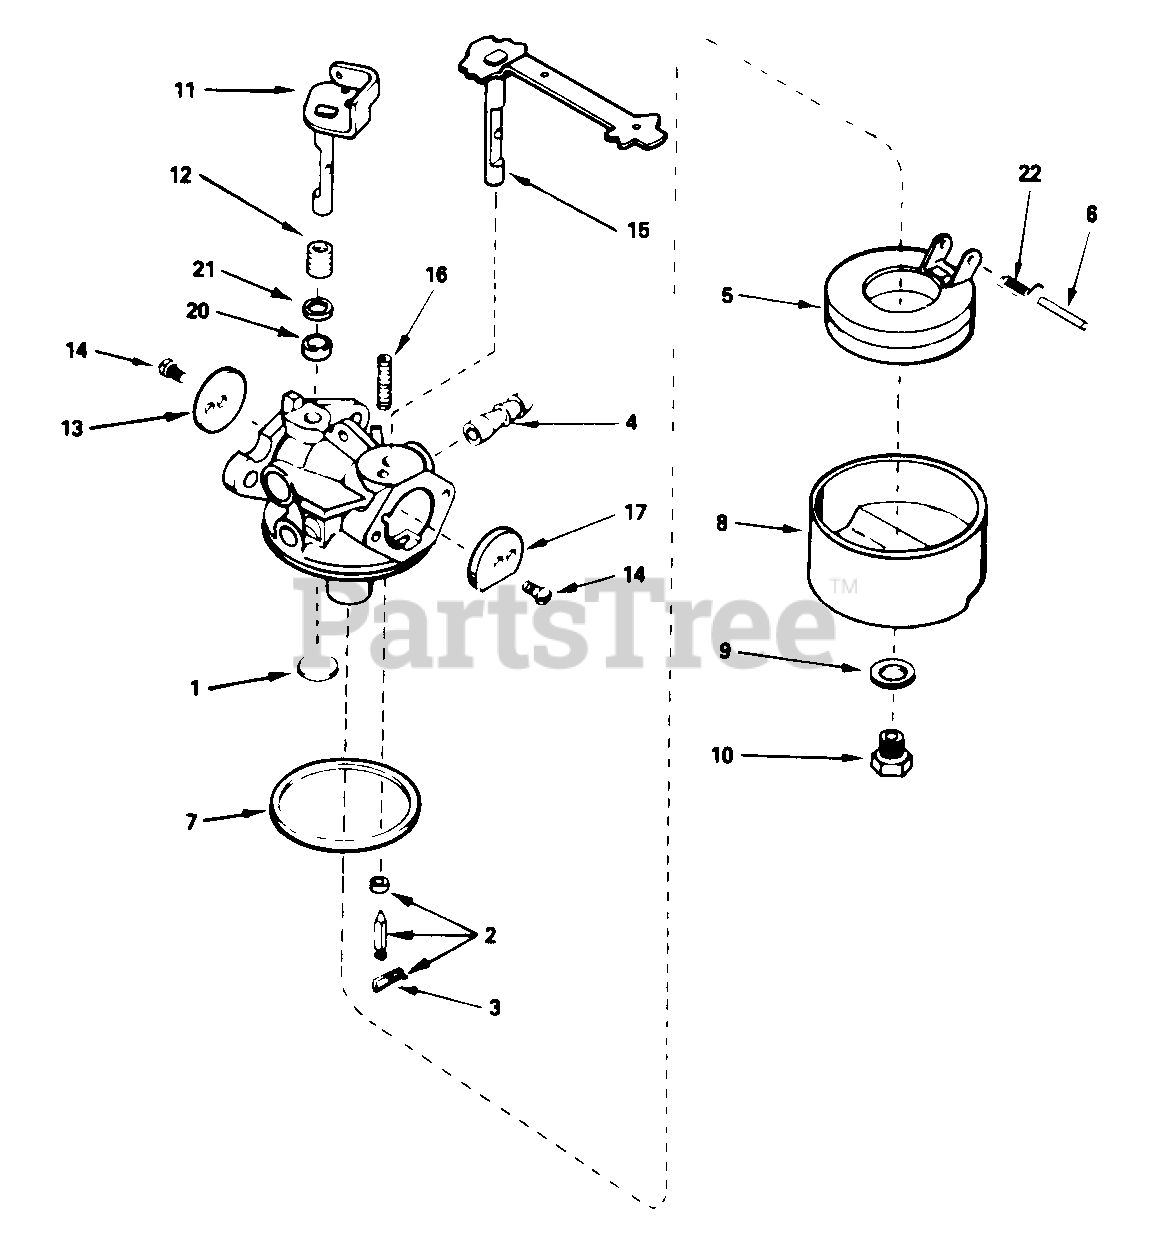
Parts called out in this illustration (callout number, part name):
1	Plug, Welch
2	Inlet Needle, Seat & Clip Ass'y
3	Clip, Inlet Needle
4	Fitting, Fuel Inlet
5	Float, Carburetor
6	Shaft, Float
7	"O"-Ring, Bowl-to-Body
8	Bowl, Float
9	Gasket, Bowl-to-Body
10	Nut, Float Bowl
11	Shaft & Lever Ass'y., Throttle
12	Spring, Throttle Return
13	Shutter, Throttle
14	Screw, Throttle & Choke Shutter
15	Shaft & Lever Ass'y., Choke
16	Spring, Choke Positioning
17	Shutter, Choke
20	Washer, Flat
21	Washer, Steel
22	Spring, Float Shaft
